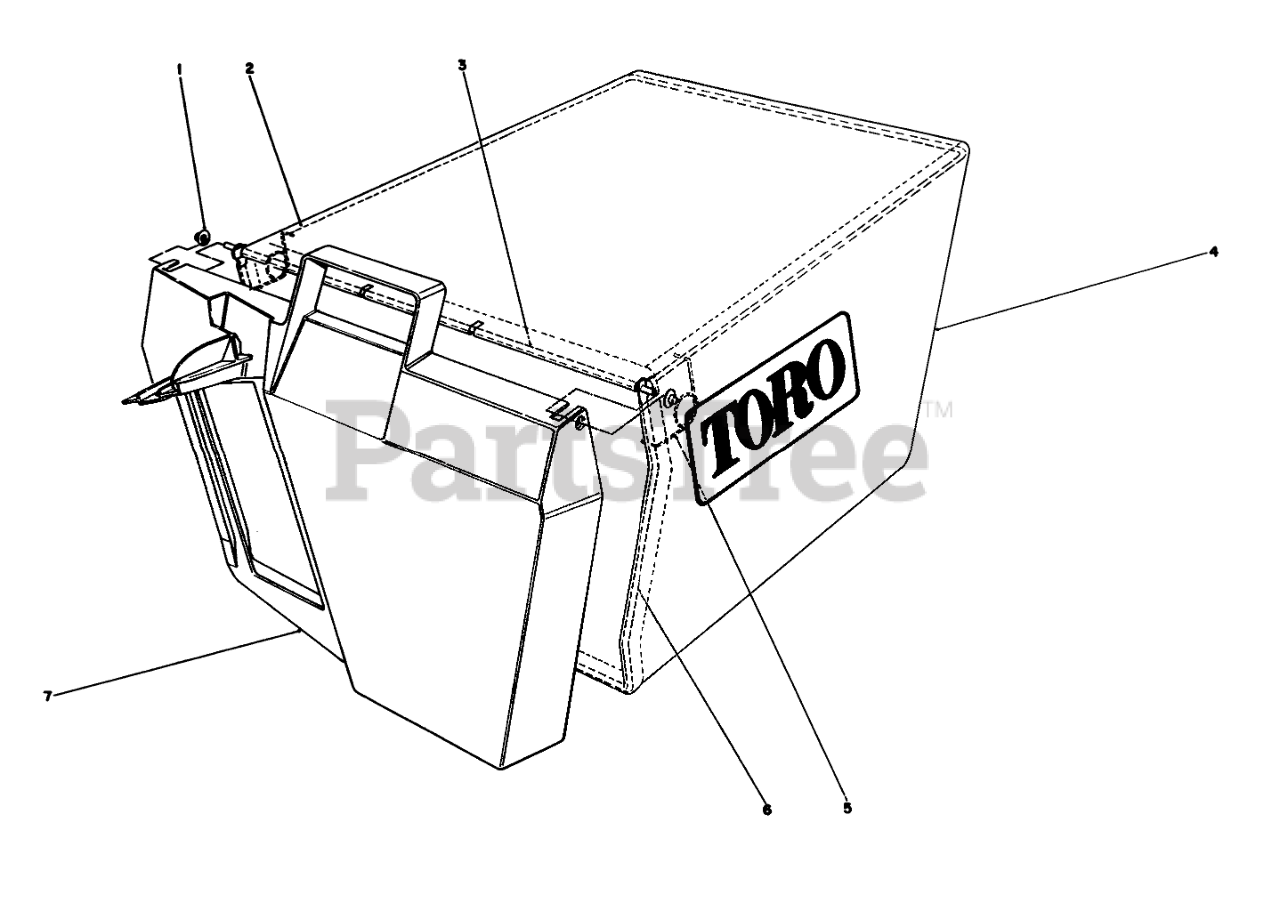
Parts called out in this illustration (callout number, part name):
1	NUT-PUSH
2	FRAME-BAG, UPPER
3	HINGE-DOOR, BAG
4	Bag
5	SPRING
6	BAG FRAME
7	BAG DOOR
